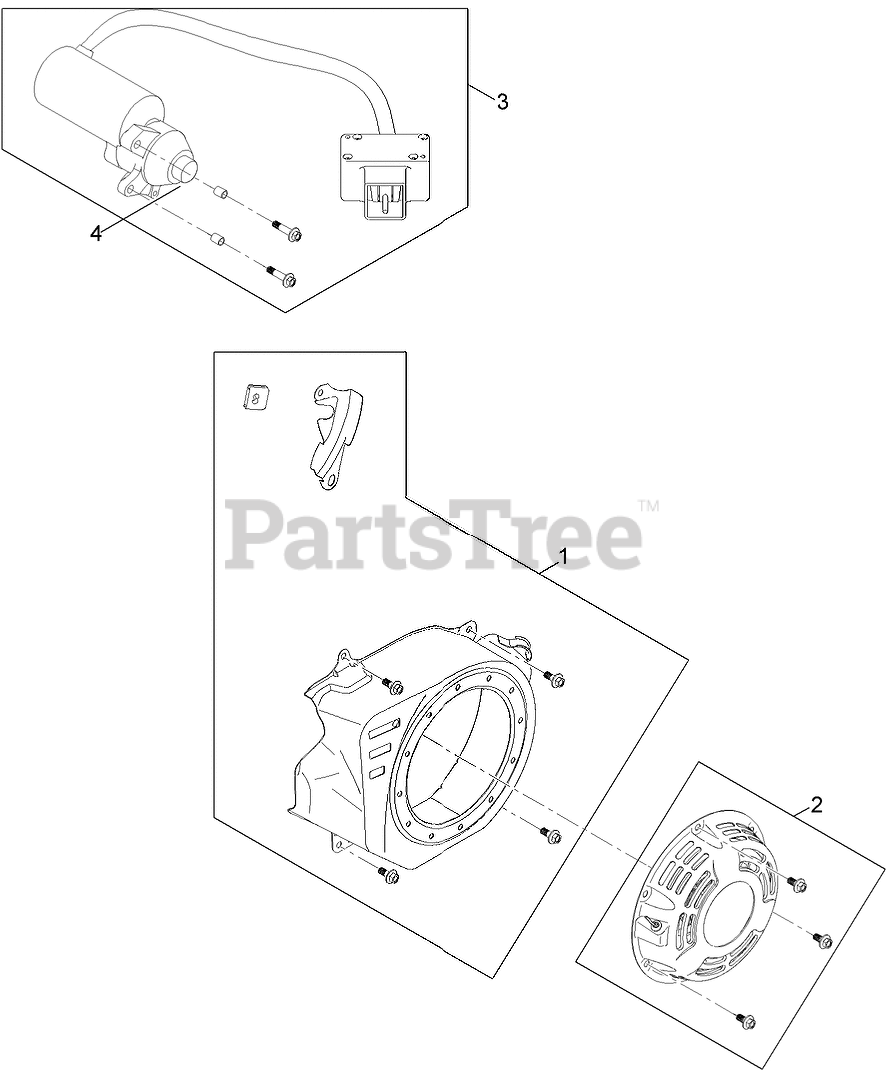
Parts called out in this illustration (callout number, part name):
1	BLOWER SHROUD KIT
2	RECOIL KIT
3	ELECTRIC STARTER KIT
4	PINION KIT
